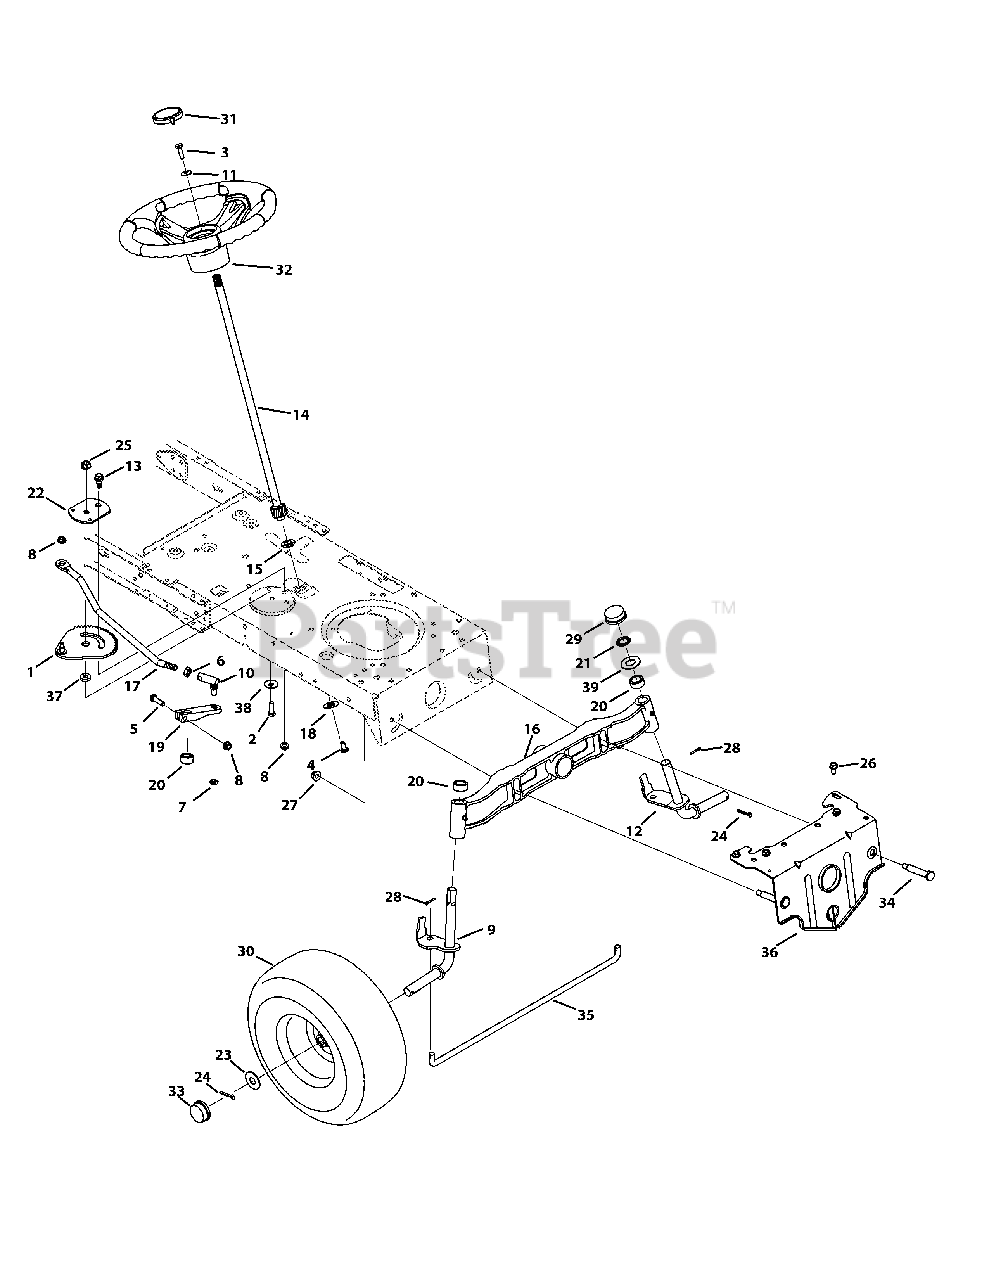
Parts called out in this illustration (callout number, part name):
1	Front Steering Gear Assembly
2	Hex Screw, 3/8-16 x 1.00
3	Hex Screw, 5/16-18 x 1.00, Lock
4	Machine Screw, 5/16-18 x .750
5	Hex Screw, 5/16-18 x 1.75
6	Jam Nut, 7/16-20
7	Jamlock Nut, 3/8-24
8	Flangelock Nut, 5/16-18
9	Front RH Axle
10	Ball Joint, 7/16-20
11	Bell Washer, .340 x .872 x .060
12	Front LH Axle
13	Shoulder Bolt, 5/16-18 x .435 x .350
14	Steering Shaft, 5/8
15	Flange Bearing, 5/8
16	Pivot Bar, Cast
17	Steering Link
18	Cap, 1.25 x .16
19	Steering Block
20	Spacer, .71 x .125 x .56
21	Push Nut 3/4 Dia.
22	Stabilizer Plate
23	Flat Washer, .781 x 1.590
24	Cotter Pin, 5/32 x 1.25
25	Flangelock Nut, 3/8-16
26	Screw, 5/16-18 x .750
27	Flangelock Nut, 3/8-16
28	Cotter Pin, .125 x .75
29	Push Cap, Cast
30	Wheel Assembly
31	Sprig Cap
32	Steering Wheel
33	Hub Cap
34	Shoulder Bolt, 3/8-16 x .500 x 2.38
35	Fixed Rod
36	Pivot Bar Bracket
37	Spacer, .38 ID x .854 OD x .20
38	Bell Washer, .390 x 1.13 x .062
39	Washer, Flat, .78 x 1.59 x .60
